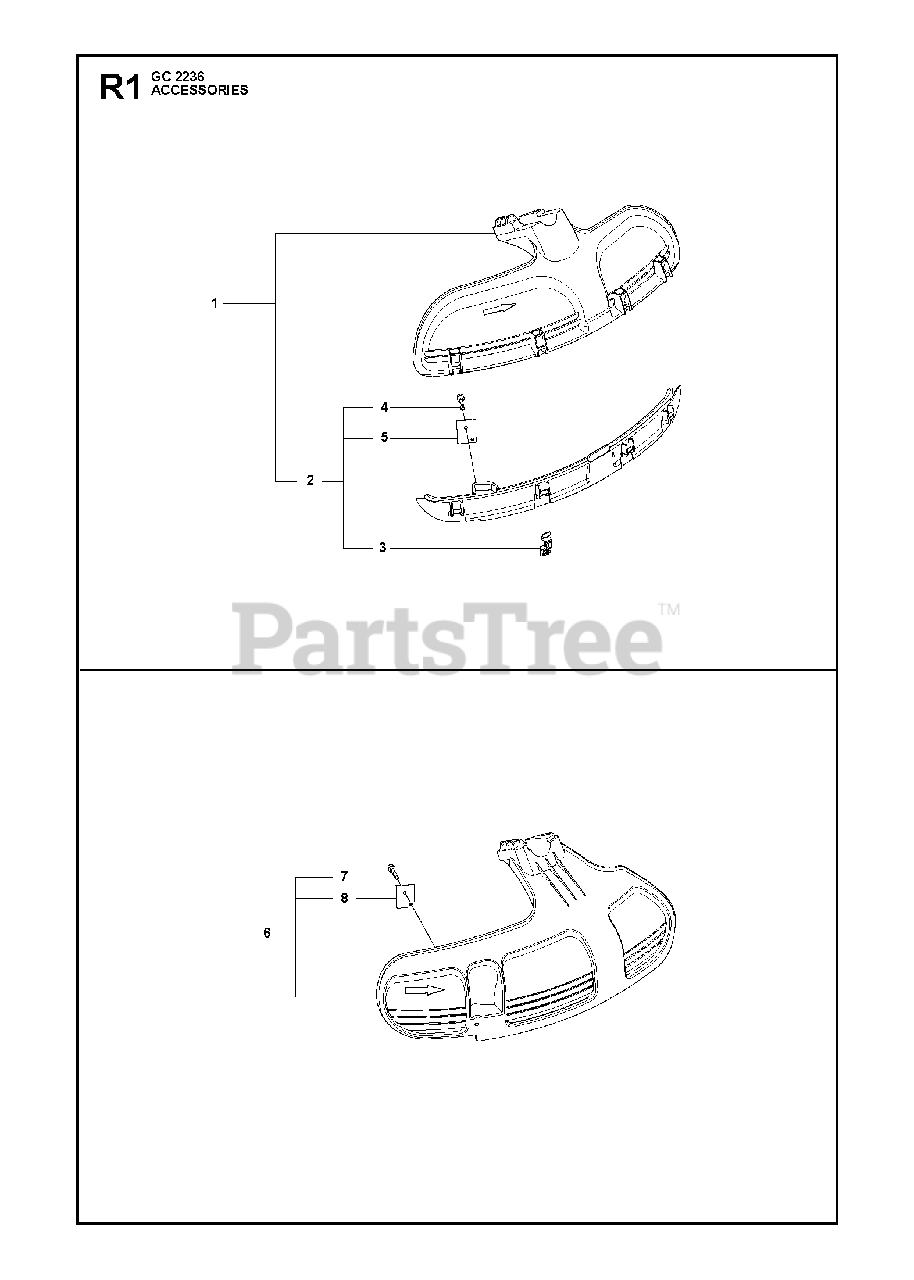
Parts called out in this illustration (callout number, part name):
1	COMBI PROTECTOR
2	SPLASH GUARD
3	BUCKLE
4	SCREW
5	LINE CUTTER
6	TRIMMER GUARD
7	SCREW
8	LINE CUTTER
